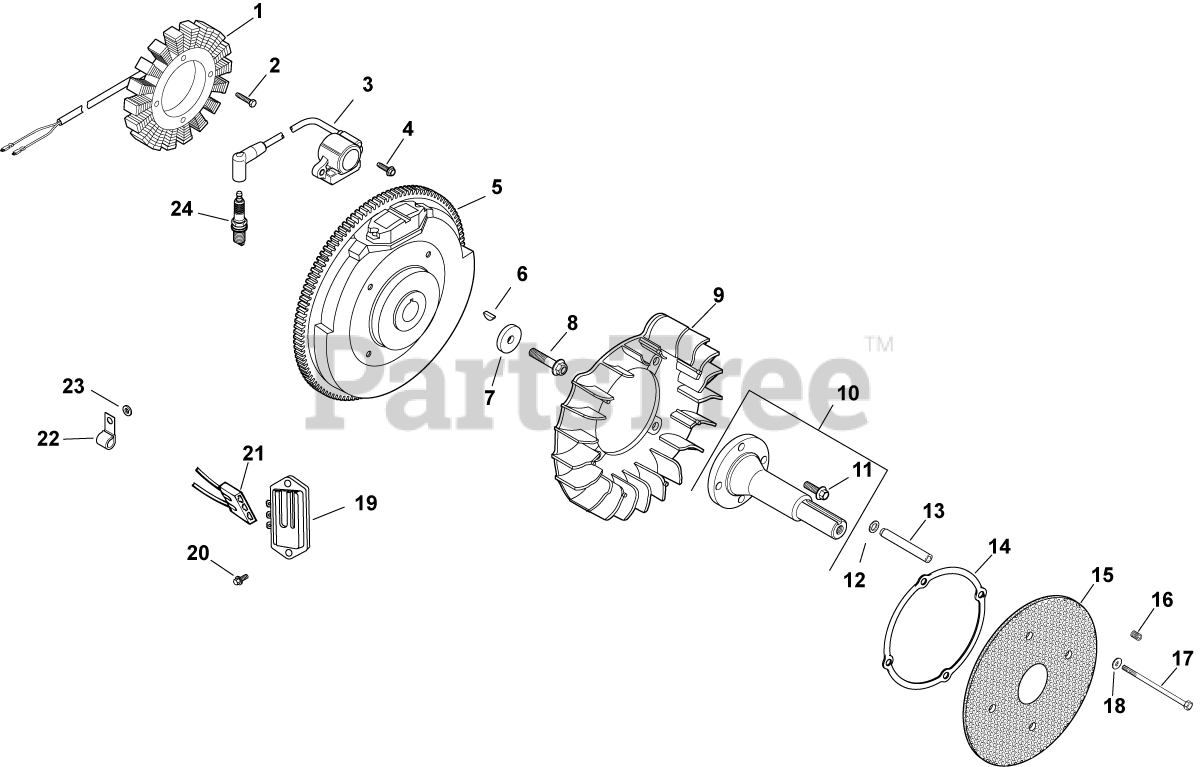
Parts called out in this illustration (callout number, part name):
1	KIT, 15 / 20 AMP STATOR
2	SCREW, M5X0.8X25 - (#25086402S)
3	KIT, MODULE IGNTN (CDI FIXED)
4	SCREW, FLG THD FRM M5X.8X20-(#25086399S)
6	KEY, 3/16" X 5/8"
7	WASHER, FLAT 13/32"
8	SCREW, FLG M10X1.5X45 - (#25086361S)
9	FAN USE 24 755 253-S
10	KIT, FRONT DRIVE SHAFT
11	SCREW, FLG M8X1.25X25
12	WASHER, SPRING 10 MM
14	RING, SUPPORT USE 25 141 08-S
15	SCREEN, GRASS
16	SCREW, SKT SET #10-24X1/4"
17	SCREW, CAP M6X1.0X99.5
18	WASHER, FLAT 1/4" (O.D. 5/8")
19	REG/RECT-15 AMP (KM)-USE 41 403 10-S
20	SCREW, HEX FLANGE HI-LO
21	CONNECTOR
22	CLIP, CABLE
23	WASHER, FLAT 1/4" (O.D. 1/2")
24	PLUG, SPARK (PRO SERIES)
